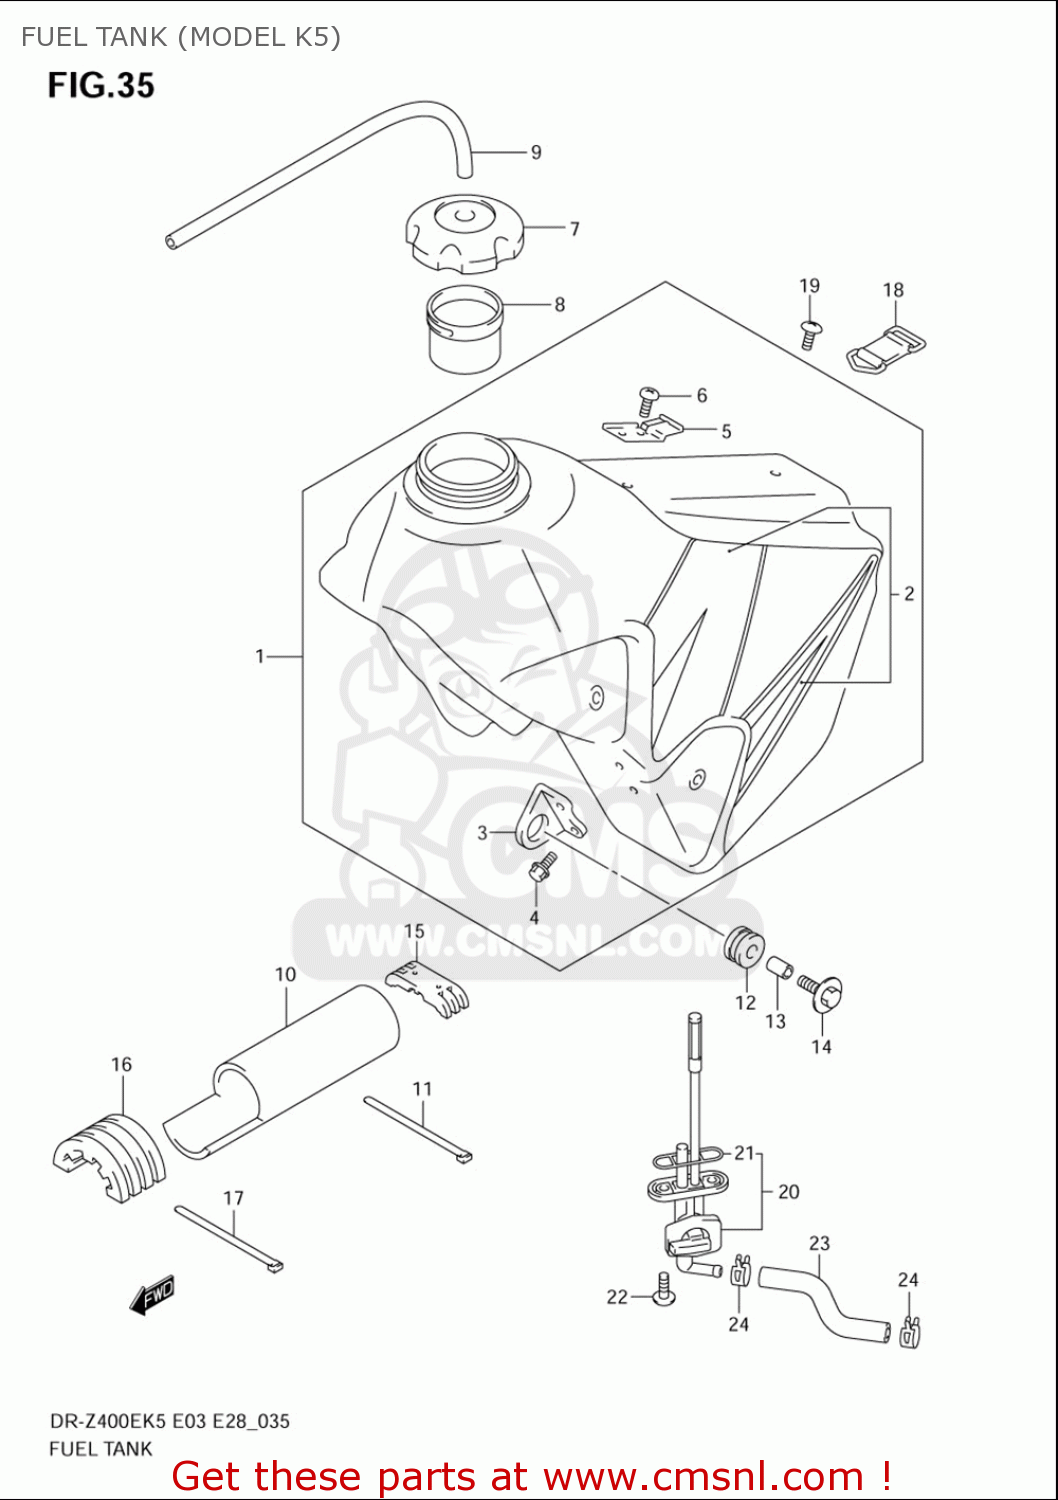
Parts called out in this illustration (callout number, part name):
1	TANK ASSY,FUEL(YELLOW)
2	TAPE SET,FUEL TANK
3	BRACKET,FUEL TANK FR
4	BOLT
5	HOOK,SEAT FR
6	SCREW
7	CAP ASSY,FUEL TANK FILLER
8	TUBE,FILLER INLET
9	HOSE(5X8.2X600)
10	SHIELD,FUEL TANK
11	CLAMP(L:300)
12	CUSHION,MUFFLER
13	SPACER(6.5X9X13.5)
14	BOLT(6X30)
15	CUSHION,FUEL TANK RR
16	CUSHION,FUEL TANK
17	CLAMP(L:300)
18	BAND,FUEL TANK RR
19	SCREW
20	COCK ASSY,FUEL
21	GASKET,JOINT (NAS)
22	BOLT
23	HOSE,FUEL
24	CLIP
